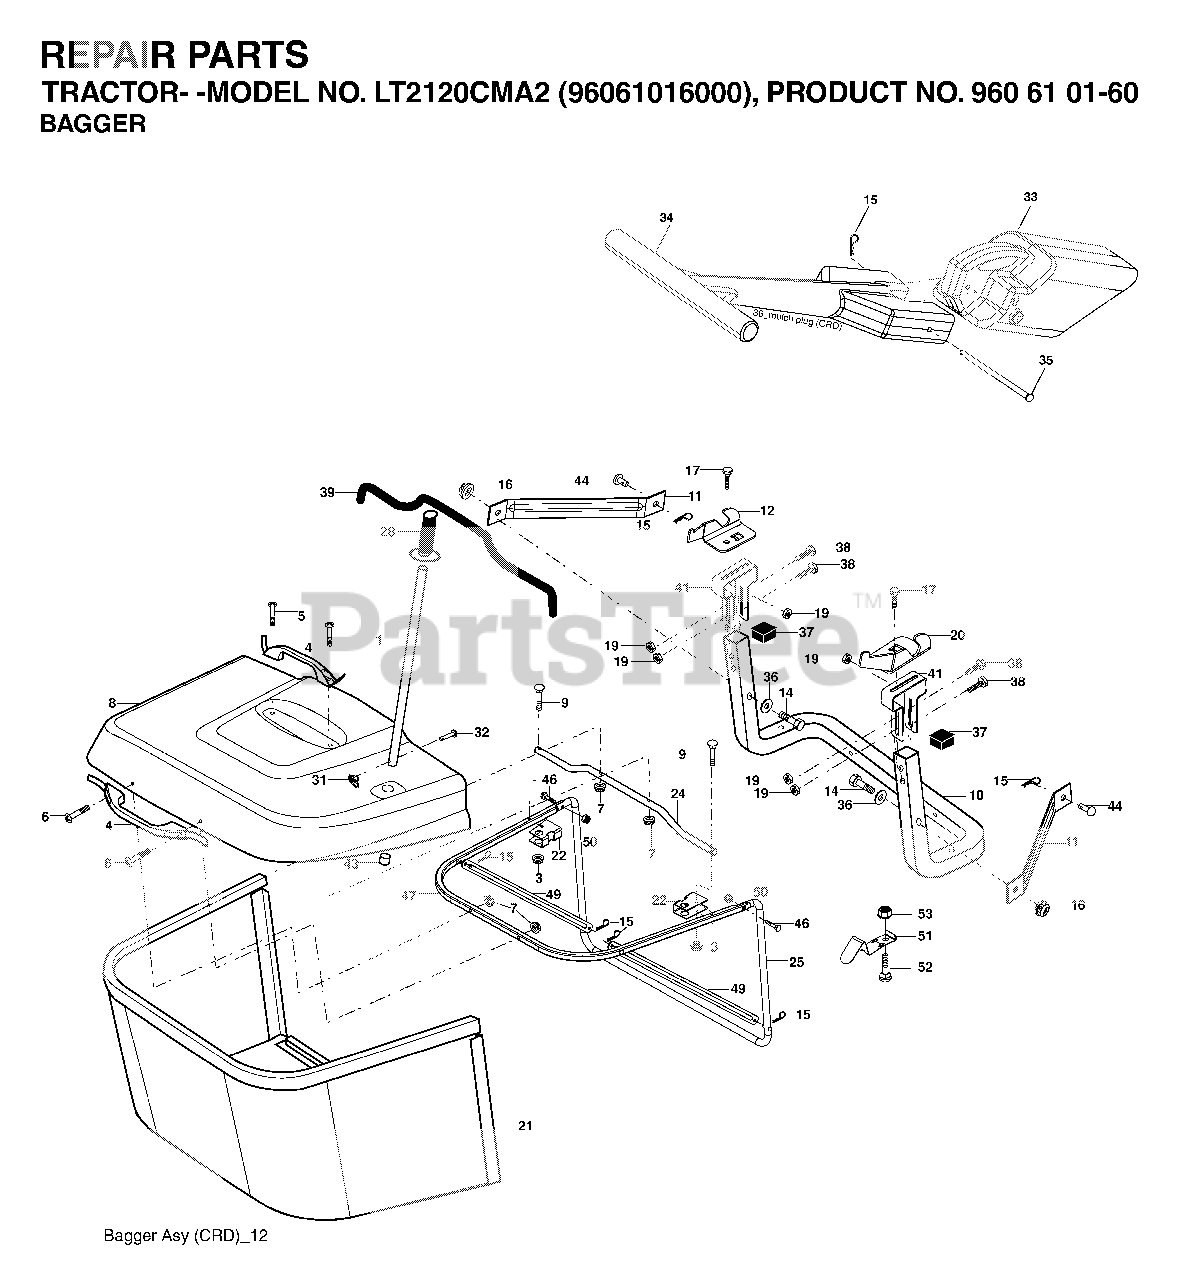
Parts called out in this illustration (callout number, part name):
1	TUBE HANDLE
3	NUT T
5	SCREW.PAN.HEAD
11	BRACKET
14	BOLT-HEX EAK
15	RETAINER-SPRNG RB
16	NUT LOCK FLG 3/8-16 UNC
17	BOLT
19	NUT LOCK HEX FLANGE 5/16-18
20	BRKT.PIVOT.RH.CRD
22	BRACKET
24	TUBE
28	GRIP.HANDLE.BLACK
31	RETAINER CLIP
32	RIVET,DRILLED
33	MULCH PLUG, CTH150
35	PIN
38	BOLT.5/16-18X2.5
41	BRKT, BAGGER
43	PLUG, TUBING END
46	BOLT.CARRIAGE.5/16-18
50	NUT.71038.31-18.HEX.NYLOCK
52	BOLT
53	NUT
